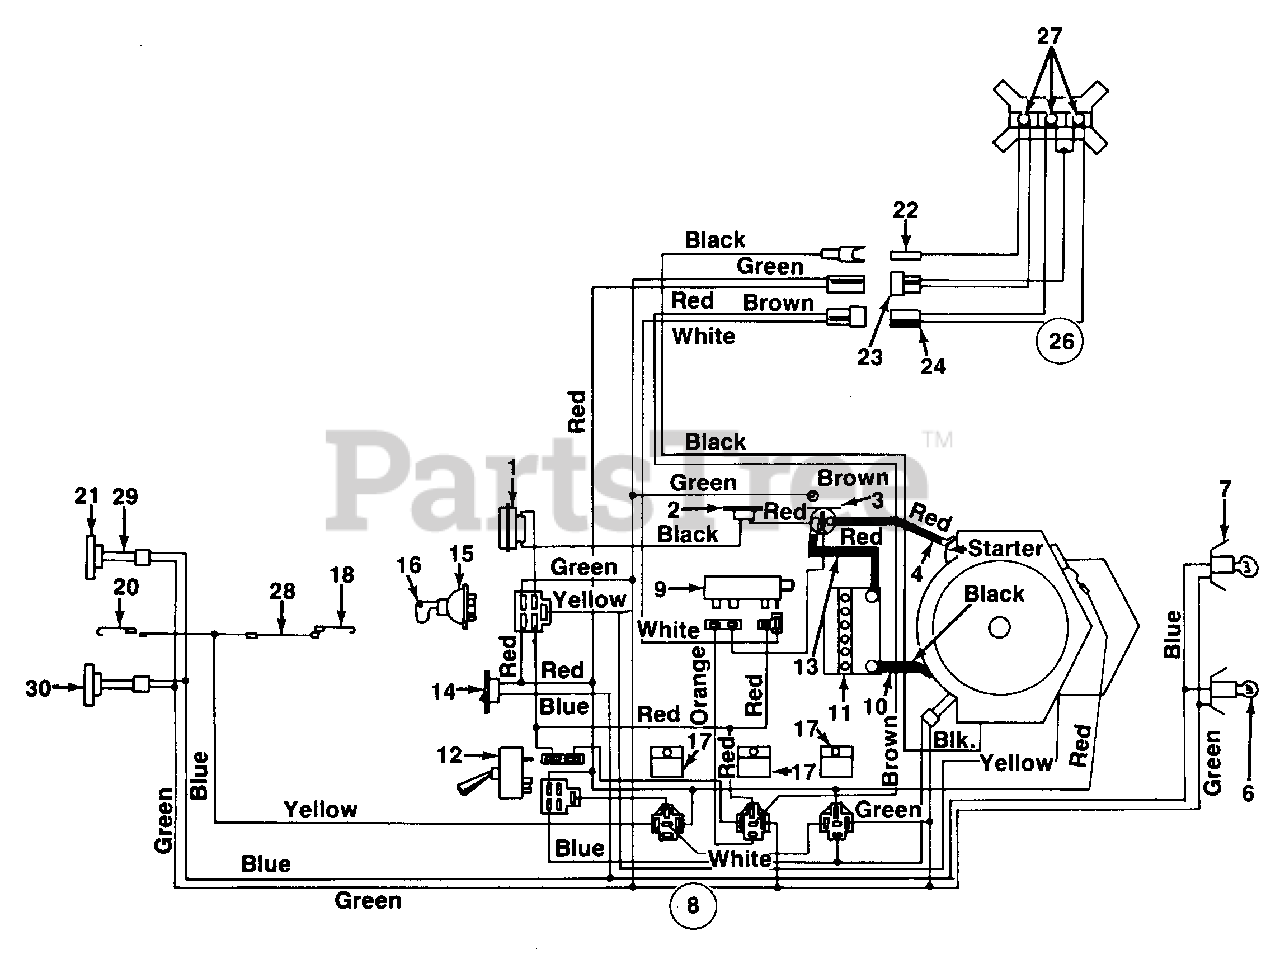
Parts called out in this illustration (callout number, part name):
1	Ammeter
2	Circuit Breaker
3	Solenoid
4	Wire
6	Bulb
7	Socket
8	Wire Harness
9	Safety Switch
10	6 Ga. Black Wire
11	Battery 12V
12	Switch
14	Light Switch
15	Ignition Switch
16	Ignition Key
17	Relay
18	Spring Lever
20	Safety Switch
21	Taillight
22	Connector
23	Connector
24	Connector
26	Wire Harness
27	Bulb
28	Transmission Ext. Wire
29	Taillight Harness
